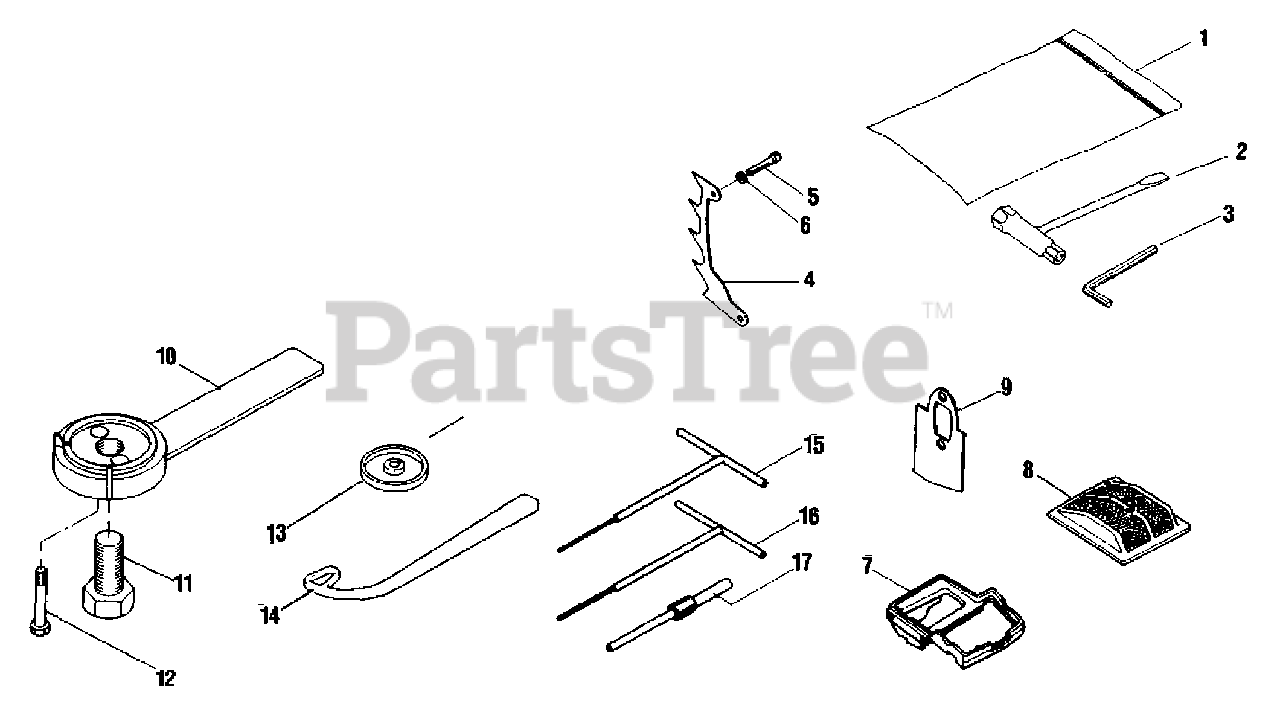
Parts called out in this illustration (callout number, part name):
1	BAG, TOOL
2	T-WRENCH
3	WRENCH - 4
5	BOLT 5×12
6	WASHER, SPRING 5
7	DUCT, AIR
8	FILTER, AIR - STAINLESS
9	GASKET, EXHAUST
11	BOLT, CENTER
13	SET GAUGE
14	FLYWHEEL WRENCH
15	T-WRENCH - 4 MM
16	T-WRENCH - 5 MM
17	PIN, SET
